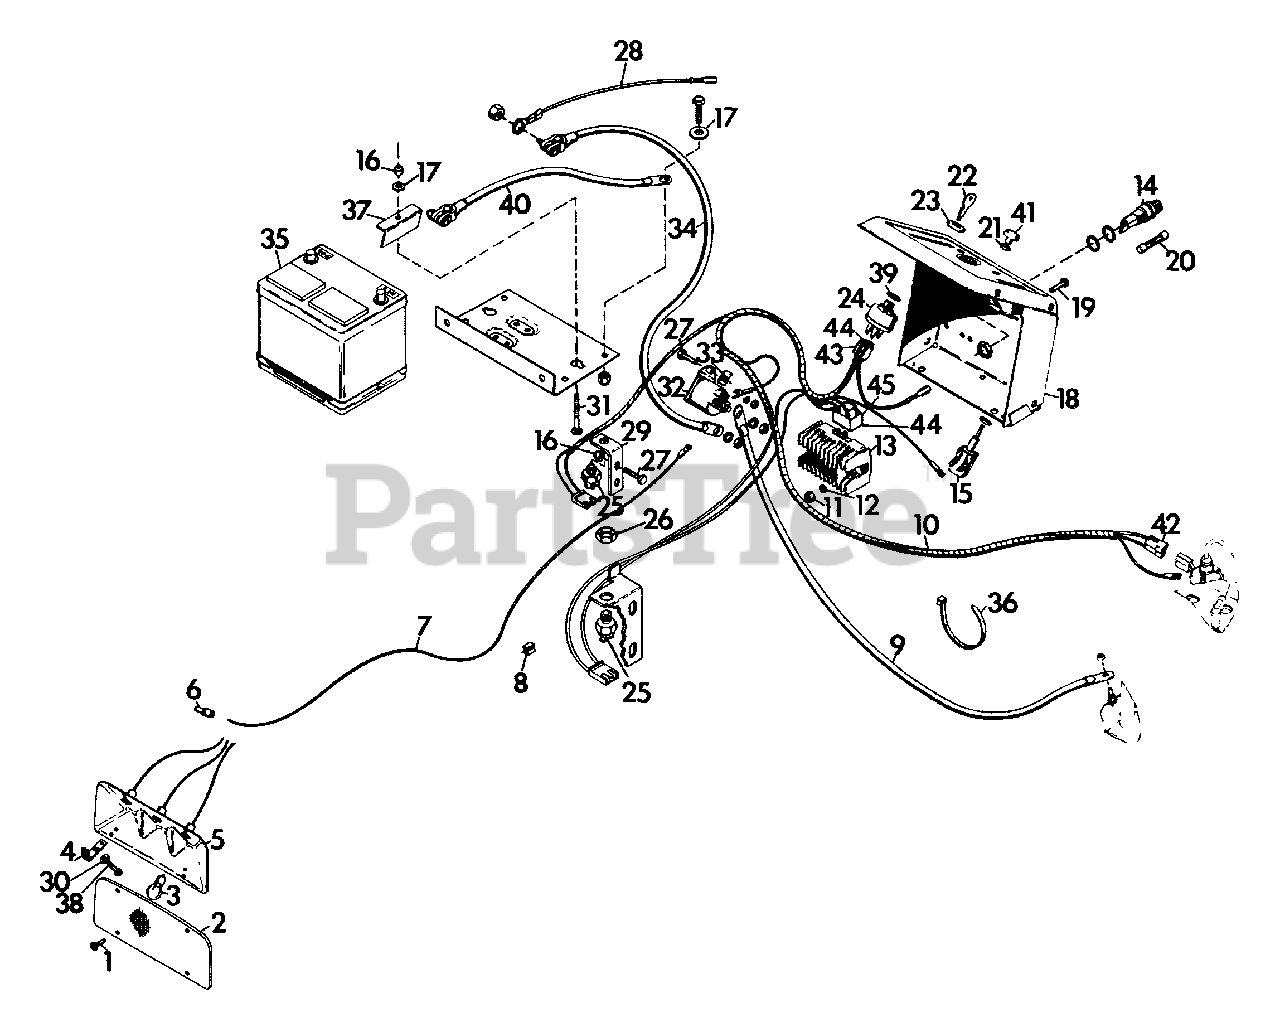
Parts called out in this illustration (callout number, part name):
1	SCREW, MACH. 10-24X.50 PHD
2	PANEL, FRONT LIGHT
3	LAMP, NO. 1073
4	CLIP, LIGHT MTG.
5	ASSEMBLY, LAMP REFLECTOR
6	NUT, WIRE
7	WIRE, HEADLIGHT
8	CLIP, WIRE
9	CABLE, STARTER
10	HARNESS, WIRING 12 HP KOHLER
11	NUT, HEX 1/4-20
12	WASHER, LOCK 1/4 REG.
13	REGULATOR, RECTIFIER
14	FUSE, PANEL
15	SWITCH, LIGHT
16	NUT, LOCK 1/4-20
17	WASHER, FLAT .281X.625X.065
18	PANEL, INSTRUMENT
19	SCREW, MACHINE 1/4-20 PAN HD
20	FUSE, 30 AMP AGC 30
21	NUT, SPECIAL LIGHT SWITCH
22	KEY, IGNITION SWITCH
23	NUT, JAM 9/16-24
24	SWITCH, IGNITION
25	SWITCH, INTERLOCK
26	NUT, STAMPED 9/16-18
27	BOLT, HEX 1/4-20X.625
28	WIRE, INSTRUMENT PANEL
29	BRACKET, SWITCH
30	WASHER, FLAT .188X.562X.049
31	BOLT, 1/4-20X1.75 RD HD SQ NK
32	SWITCH, MAGNETIC
33	NUT, SPEED 1/4-20
34	CABLE, BATTERY TO MAGNETIC SWITCH
35	BATTERY, 12 VOLT
36	TIE, CABLE
37	CLAMP
38	SCREW, MACH. 10-24X.75 PHD
39	WASHER, LOCK 9/16 INT. TOOTH
40	CABLE, NEGATIVE BATTERY
41	KNOB, LIGHT SWITCH
42	CONNECTOR
43	CONNECTOR
44	TERMINAL
45	CONNECTOR
NS	BOOT, BATTERY CABLE
NS	WASHER, LCOK 1/4 EXT. TOOTH TYPE A
